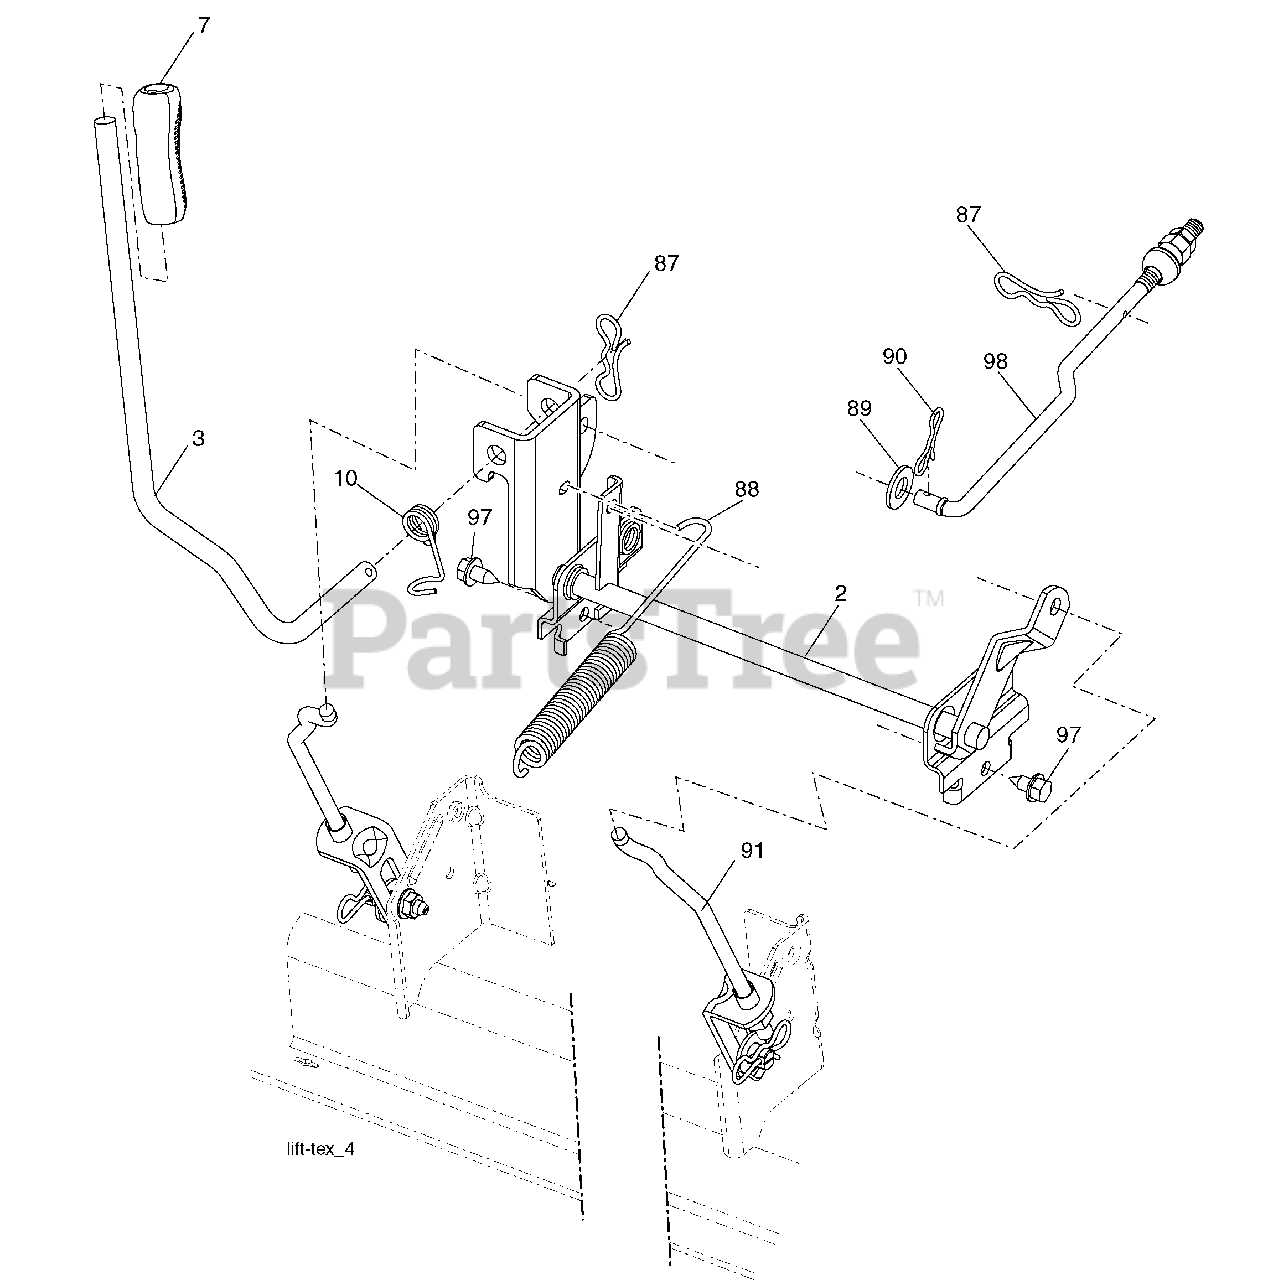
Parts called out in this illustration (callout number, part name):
2	Shaft Asm., Lift
3	Lever Asm., Lift Rh
7	Grip, Lever
10	Spring Torsion
87	Pin Cotter 7/16 Bow Tie Lock
88	Spring Lift Assist
89	Washer Clear Zinc
90	Pin Cotter 5/16 Bow Tie Lock
91	Link Asm. Lift Rear
97	Screw 3/8-16 x .75 Smgml Tap/R.Z
98	Link Lift Susp. Front Mower
